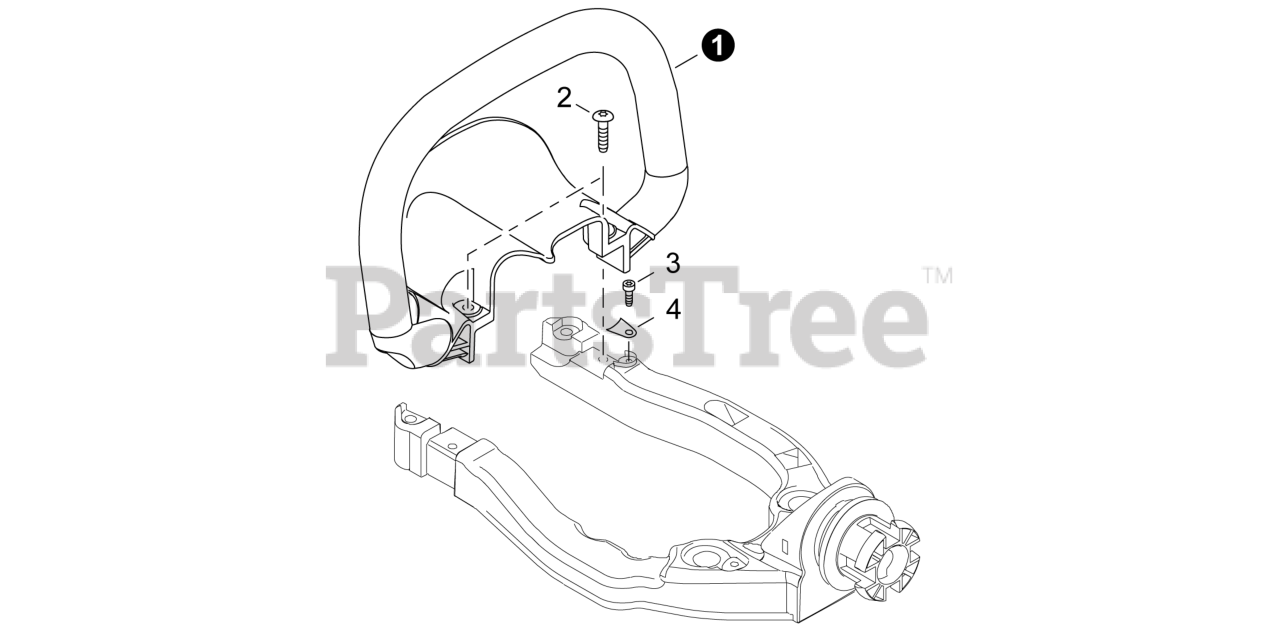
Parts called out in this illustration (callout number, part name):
1	HANDLE, FRONT
2	BOLT, TORX 6x25
3	BOLT, TORX 4x12
4	PLATE, EYE
